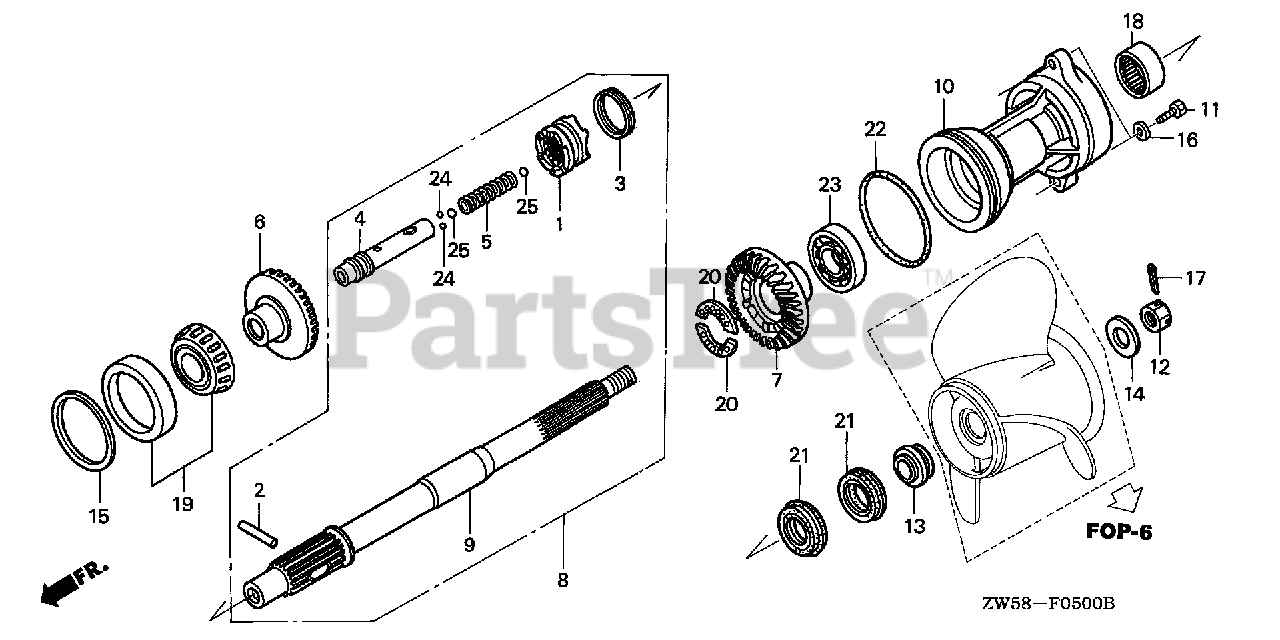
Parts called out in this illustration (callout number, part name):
1	SHIFTER, CLUTCH
2	PIN, SHIFTER (8X47)
3	RING, CROSS PIN
4	SLIDER, SHIFT
5	SPRING, SHIFT
6	GEAR, BEVEL (F)
7	GEAR, BEVEL (R)
8	SHAFT ASSY., PROPELLER
9	SHAFT, PROPELLER
10	HOLDER, PROPELLER SHAFT *NH282MU* (OYSTER SILVER METALLIC-U)
11	BOLT, HEX. (10X40)
12	NUT, CASTLE (18MM)
13	WASHER, PROPELLER THRUST
14	WASHER, PLAIN (18.5MM)
15	SHIM A, BEVEL (0.10) (FR)
15	SHIM B, BEVEL (0.15) (FR)
15	SHIM C, BEVEL (0.30) (FR)
15	SHIM D, BEVEL (0.50) (FR)
16	WASHER, PLAIN (10MM)
17	PIN, SPLIT (4.0)
18	BEARING, NEEDLE (30X37X26)
19	BEARING, TAPERED (50X82X21.5)
20	BEARING, BALL (28X38X3)
21	SEAL, WATER (30X45X7)
22	O-RING (94X4.1)
23	BEARING, RADIAL BALL (6208)
24	BALL, STEEL (#6) (3/16)
25	BALL, STEEL (#11) (11/32)
